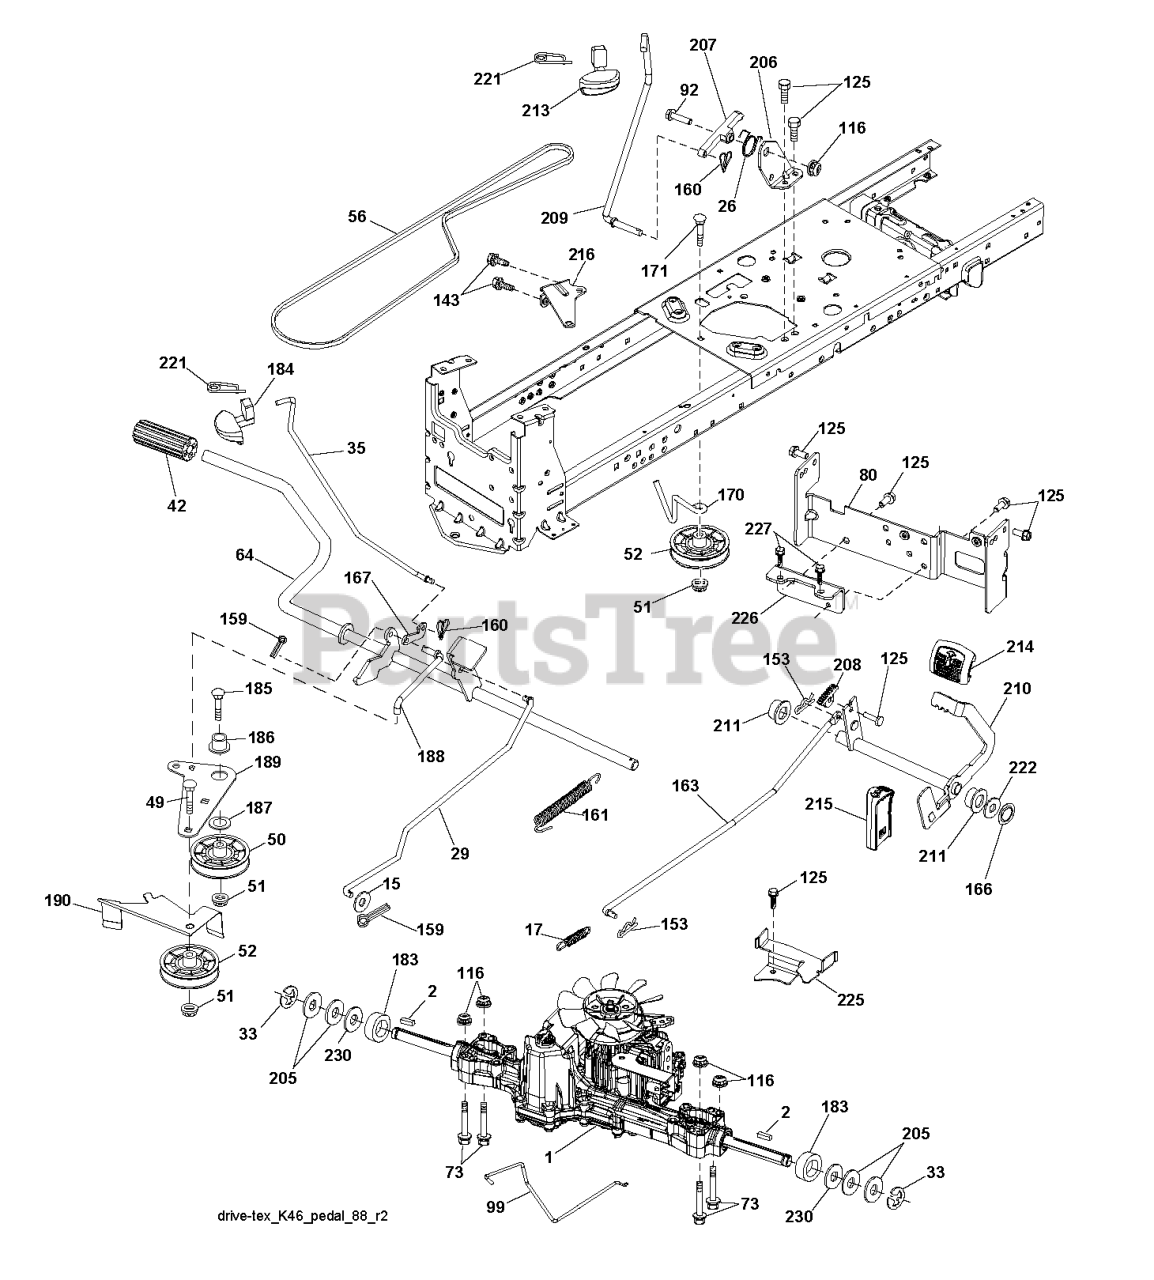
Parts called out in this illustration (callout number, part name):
2	SQUARE KEY
15	WASHER
17	SPRING.BRAKE.K46.GREEN
26	SPRING.RETURN.CRUISE
29	ROD.BRAKE.K46
35	ROD.BRAKE.PARTK.HUSQ.TEX
42	PEDAL COVER T
50	IDLER.FLAT.910.OFFSET
51	NUT LOCK FLG 3/8-16 UNC
52	IDLER.V-GROOVE.910.OFFSET
56	V-BELT.MOWER.92.40.42/K46
64	SHAFT.ASM.PEDAL.BRK.CNTR
73	BOLT
80	STRAP.TORQUE.K46.K57R.TT
92	BOLT
99	ROD.SPRING.BYPASS.K46.LT.Z
116	NUT LOCK HEX FLANGE 5/16-18
125	SCREW
143	SCREW LT
153	RETAINER M
159	COTTER PIN
160	RETAINER CLIP
161	SPRING, RETURN LT
163	ROD.CONTROL.K57R.K46
166	NUT.PUSH.625
167	LATCH.BRAKE.SPRING
170	KEEPER.V-IDLER.CENTER.
171	BOLT
183	SPACER AXLE
184	RB HANDLE.PARKG.BRK.HUS/PRED
186	SPACER.RETAINER
187	WASHER 12/32X2X10GA
188	RP.LINK.CLUTCH.GROUND.DRIVE
189	BELLCRANK.GROUND.DRIVE.TEX.
190	KEEPER.BELLCRANK.DRIVE
206	BRKT.MOUNT.LATCH.CRUIS
207	LATCH.CONTROL.CRUISE
208	GEAR.SECTOR.CONTROL.CR
209	ROD.CONTROL.CRUISE.GT.
210	ROCKER.ASM.PEDAL.CONTR
211	BEARING.NYLON
213	KNOB.CONTROL.CRUSIE.HU
214	PEDAL.FORWARD.PAD.TEX
215	PEDAL.REVERSE.TEX.GT.4
216	BRACKET.PULLEY.IDLER.W/TEX
221	RETAINER.SPRING.CLIP.H
222	WASHER 21/32 X 1-1/4 X 10 GA.
225	KEEPER.BELT.TRANSAXLE.K46
226	BRACKET.MOUNT.TORQUE.K46.TLT
227	SCREW.THDROL.5/16-18X3/4.TTY
230	WASHER.HARDENED
